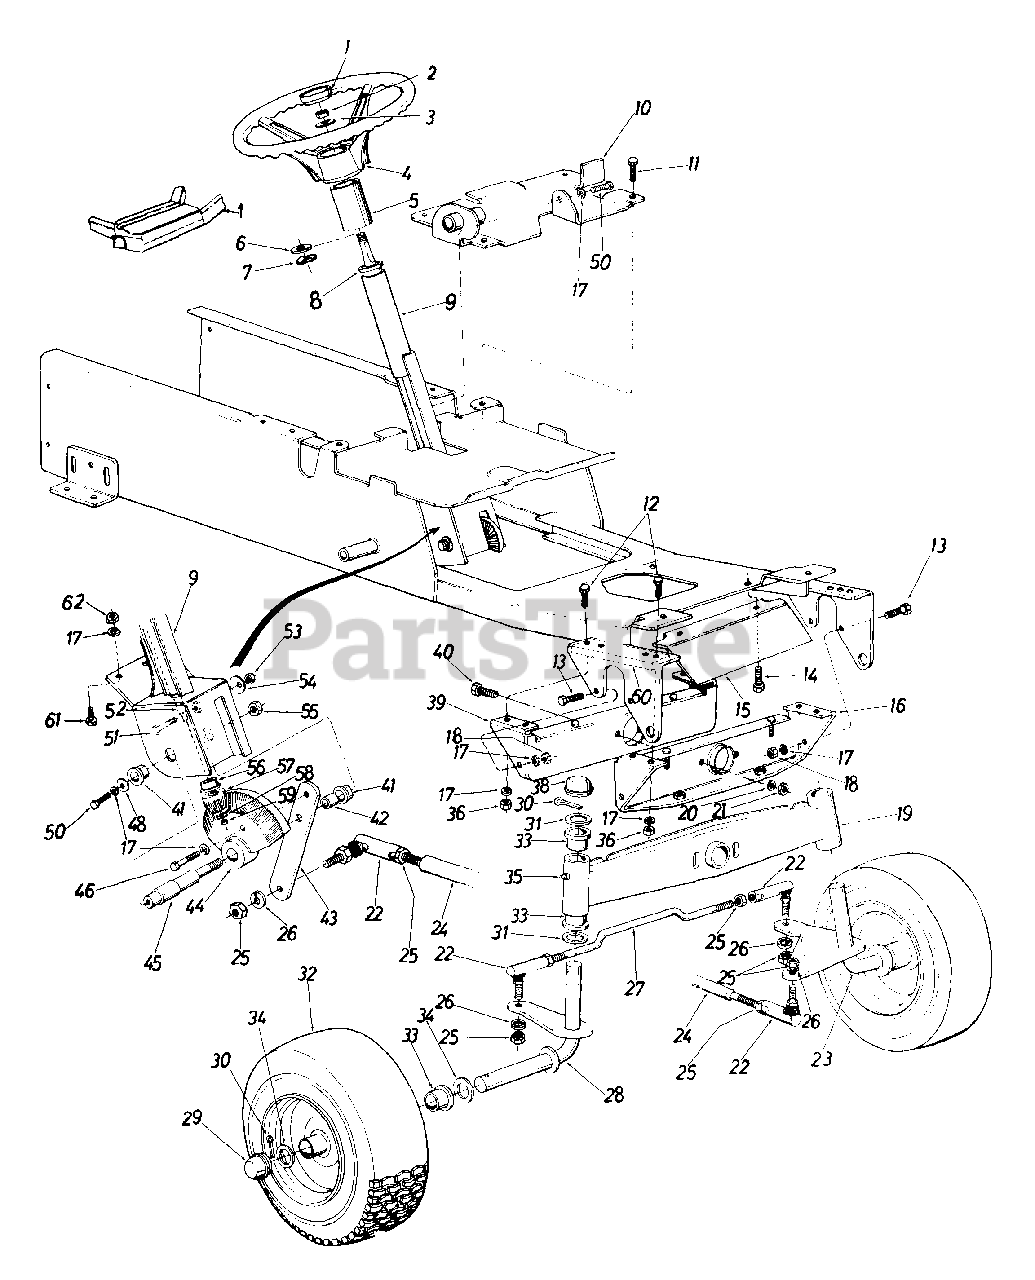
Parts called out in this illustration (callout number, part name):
1	Steering Wheel Cap
2	Hex Cent. L-Nut 5/16-18 Thd.
4	Steering Wheel
5	Steering Tube - Outer
6	Double "D" Fl-Wash.
7	Wave Wash. .660" I.D. x .88" O.D.
8	Ball Brg. .63" I.D. x 1.38" O.D.
10	Dash Panel Base Plate Ass'y.
11	Hex Self-Tap Scr. 3/8-16 x .75" Lg.
12	Hex Bolt 3/8-16 x 1.50" Lg.
13	Hex Bolt 3/8-16 x 1.00" Lg.
14	Hex Wash. S.F. Tap Scr. 3/8-16 x 1.25" Lg.
15	Dust Shield
18	Hex Nut 3/8-16 Thd.
19	Pivot Bar Ass'y.
20	Bell-Wash. 3/8" I.D.
21	Hex Cent. L-Nut 3/8-16 Thd.
22	Drag Link End
23	Axle Ass'y. - L.H.
25	Hex Nut 1/2-20 Thd.
26	L-Wash. 1/2" I.D.
28	Axle Ass'y. - R.H.
30	Cotter Pin 3/16" Dia. x 1.50" Lg.
31	Fl-Wash. 1.00" I.D. x 1.62" O.D.
33	Flange Brg. .757" I.D.
34	Fl-Wash. .635" I.D. x 1.12" O.D.
35	Grease Fitting
36	Hex Nut 3/8-16 Thd.
38	Dust Cover
41	Flange Brg. w/Flats .753" I.D.
42	Steering Gear Shaft Spacer
43	Steering Arm
44	Bevel Gear
45	Steering Gear Shaft
46	Hex Bolt 3/8-16 x 1.50" Lg.
48	Fl-Wash. .406" I.D. x 1.25" O.D.
50	Hex Bolt 3/8-16 x .75" Lg.
51	Nylon Hex Bolt 3/8-16 x 1.25" Lg.
52	Steering Shaft
53	Hex Jam Nut 3/8-16 Thd.
54	Bell-Wash. .400" I.D. x 1.13" O.D.
55	Hex Ins. L-Nut 1/2-20 Thd.
56	Hex Flange Brg. .630 I.D.
57	Pinion Gear
58	Fl-Wash. 3/8" Dia.
59	Hex Cent. L-Nut 5/16-24 Thd.
62	Hex Nut 3/8-24 Thd.
